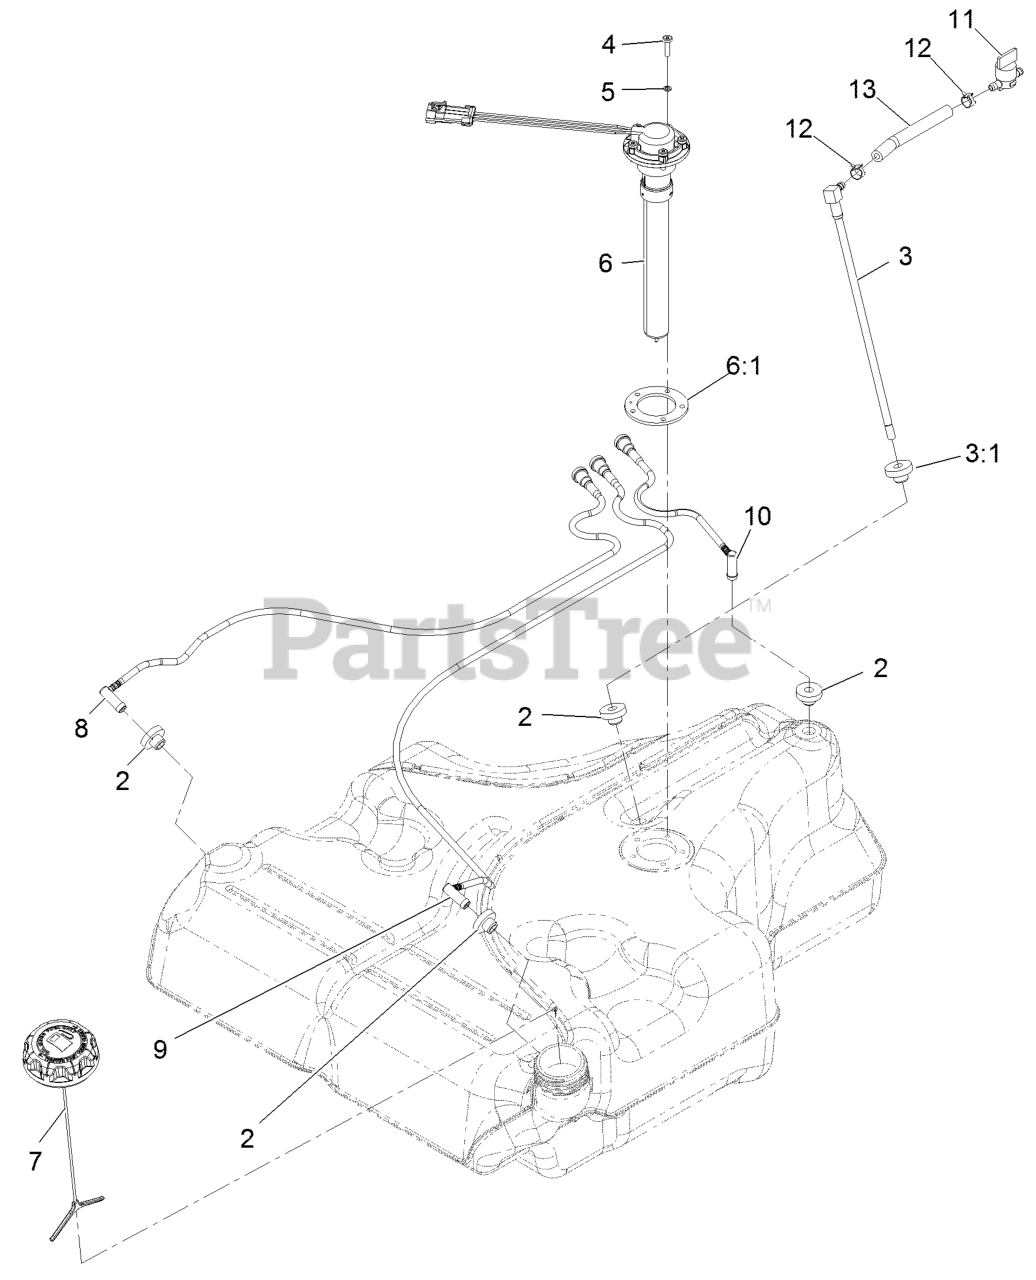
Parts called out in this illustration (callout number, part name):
2	BUSHING
3	FUEL LINE KIT (WITH GROMMET)
3:1	BUSHING
4	SCREW-PAN
5	WASHER-LOCK
6:1	GASKET-SENDER, FUEL
7	CAP-FUEL, RATCHETING
8	RH VENT LINE KIT (WITH GROMMET)
9	LH VENT LINE KIT (WITH GROMMET)
10	REAR VENT LINE KIT (WITH GROMMET)
11	VALVE-FUEL
12	CLAMP-HOSE
13	HOSE-FUEL
